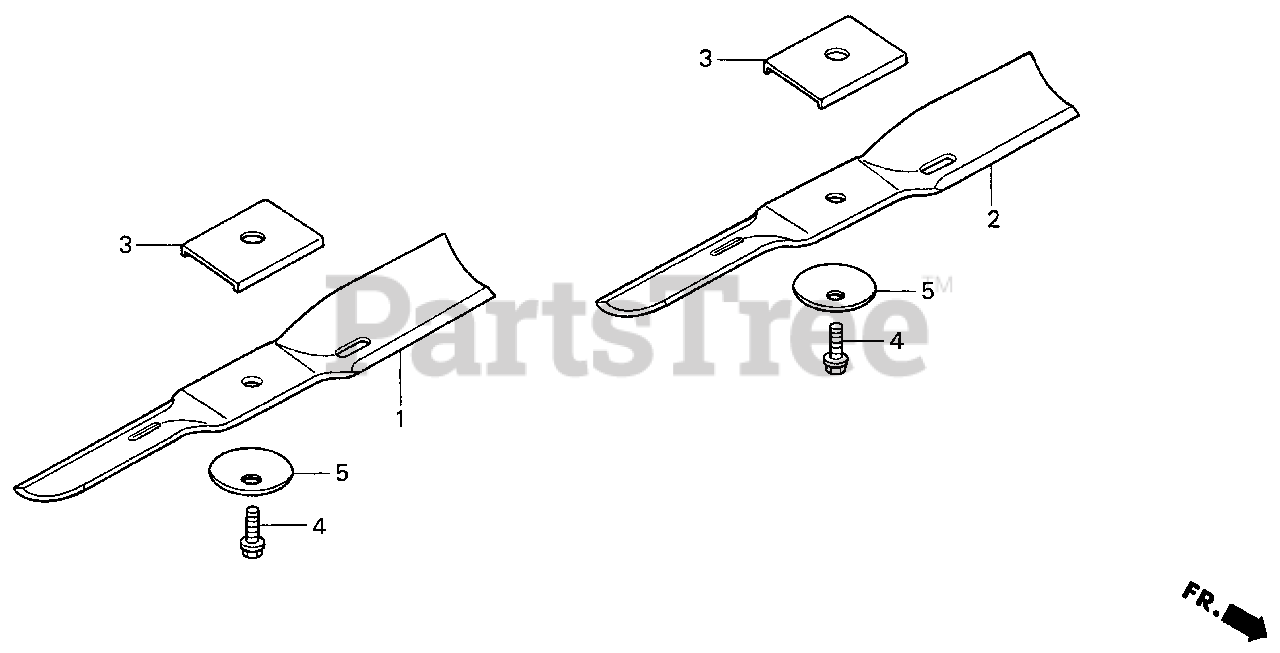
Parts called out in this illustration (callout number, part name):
1	BLADE, R. ROTARY
1	BLADE, L. ROTARY
2	BLADE, L. ROTARY
3	HOLDER, BLADE (B)
4	BOLT, BLADE HOLDER (10X28)
5	WASHER, BLADE
